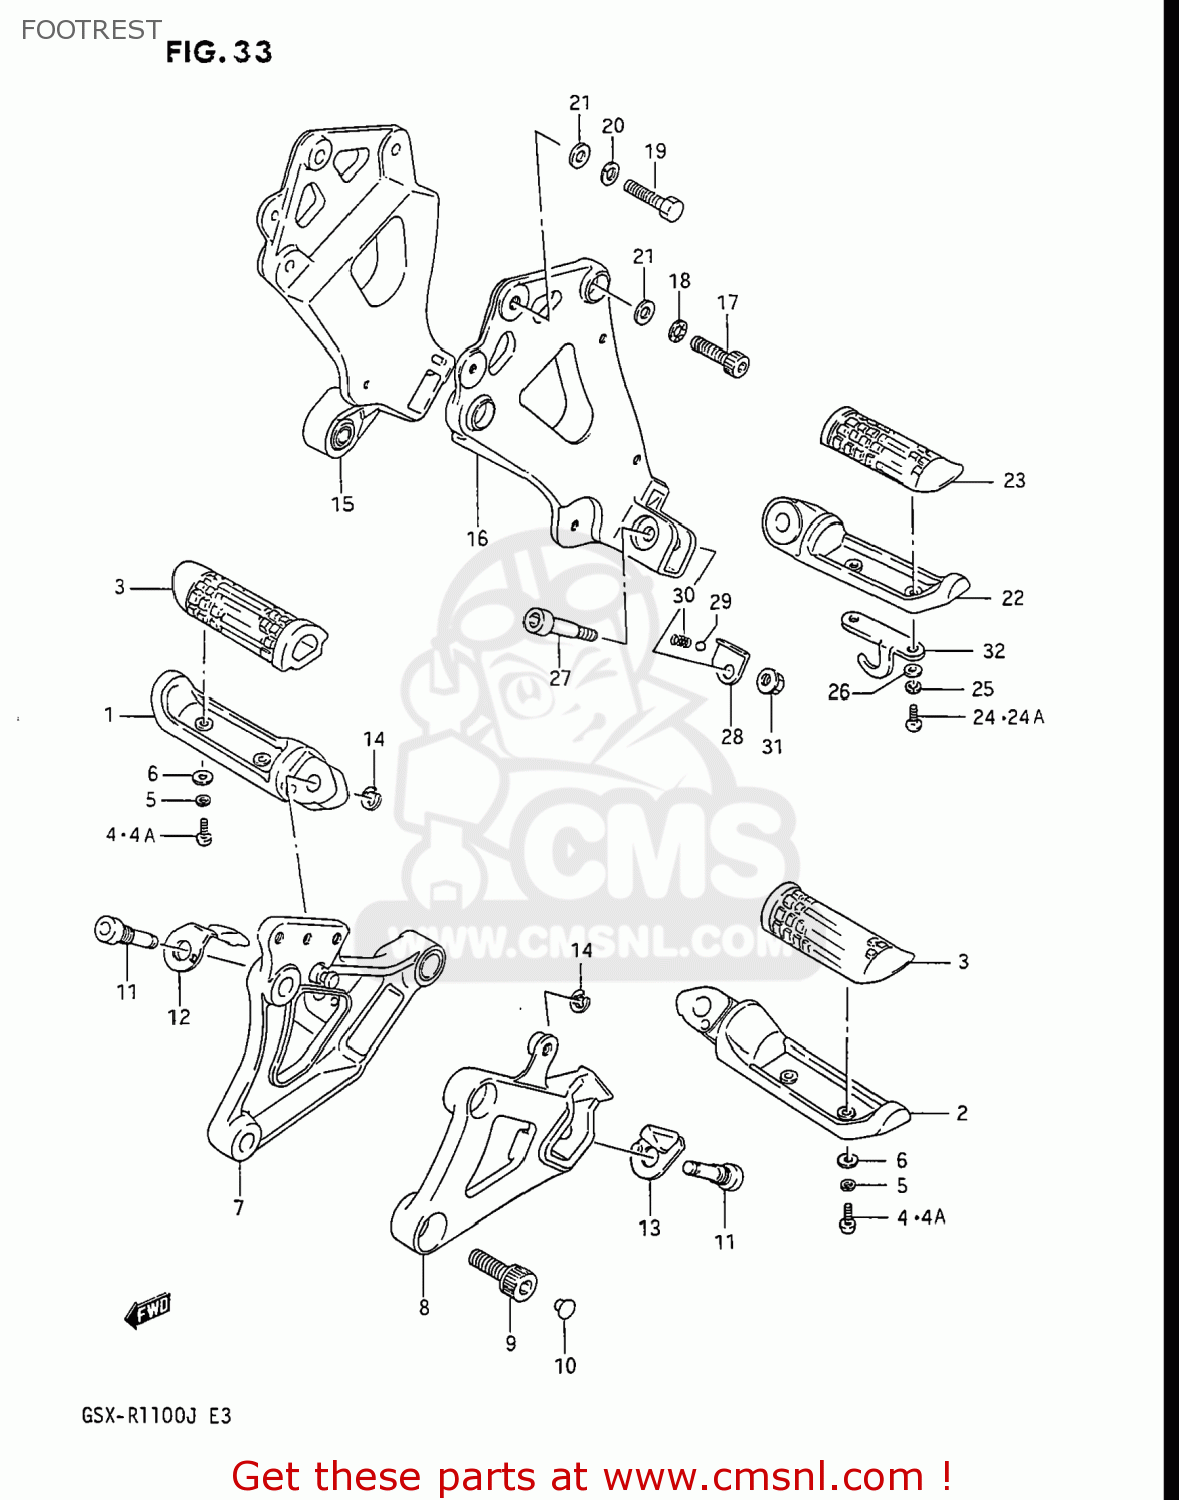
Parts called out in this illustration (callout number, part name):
1	FOOTREST ASSY,FR,R
2	FOOTREST ASSY,FR,L
3	RUBBER ASSY,FR FOOTREST
4	SCREW 5X20
4A	SCREW
5	LOCK WASHER
6	WASHER
7	BRACKET,FOOTREST,R
8	BRACKET,FOOTREST,L
9	BOLT
10	CAP
11	BOLT,FR FOOTREST
12	CUSHION,FR FOOTREST,R
13	CUSHION,FR FOOTREST,L
14	E RING 6MM
15	BRACKET
16	BRACKET
17	BOLT
18	WASHER
19	BOLT 6X30
20	WASHER,LOCK
21	WASHER
22	FOOTREST ASSY,PILLION,L
23	RUBBER,PILLION FOOTREST
24	SCREW(5X25)
24A	SCREW 5X20
25	WASHER,LOCK
26	WASHER,5MM
27	BOLT,PILLION FOOTREST
28	PLATE,SPRING STOP LH
29	BALL
30	SPRING
31	NUT
32	HOOK RH
